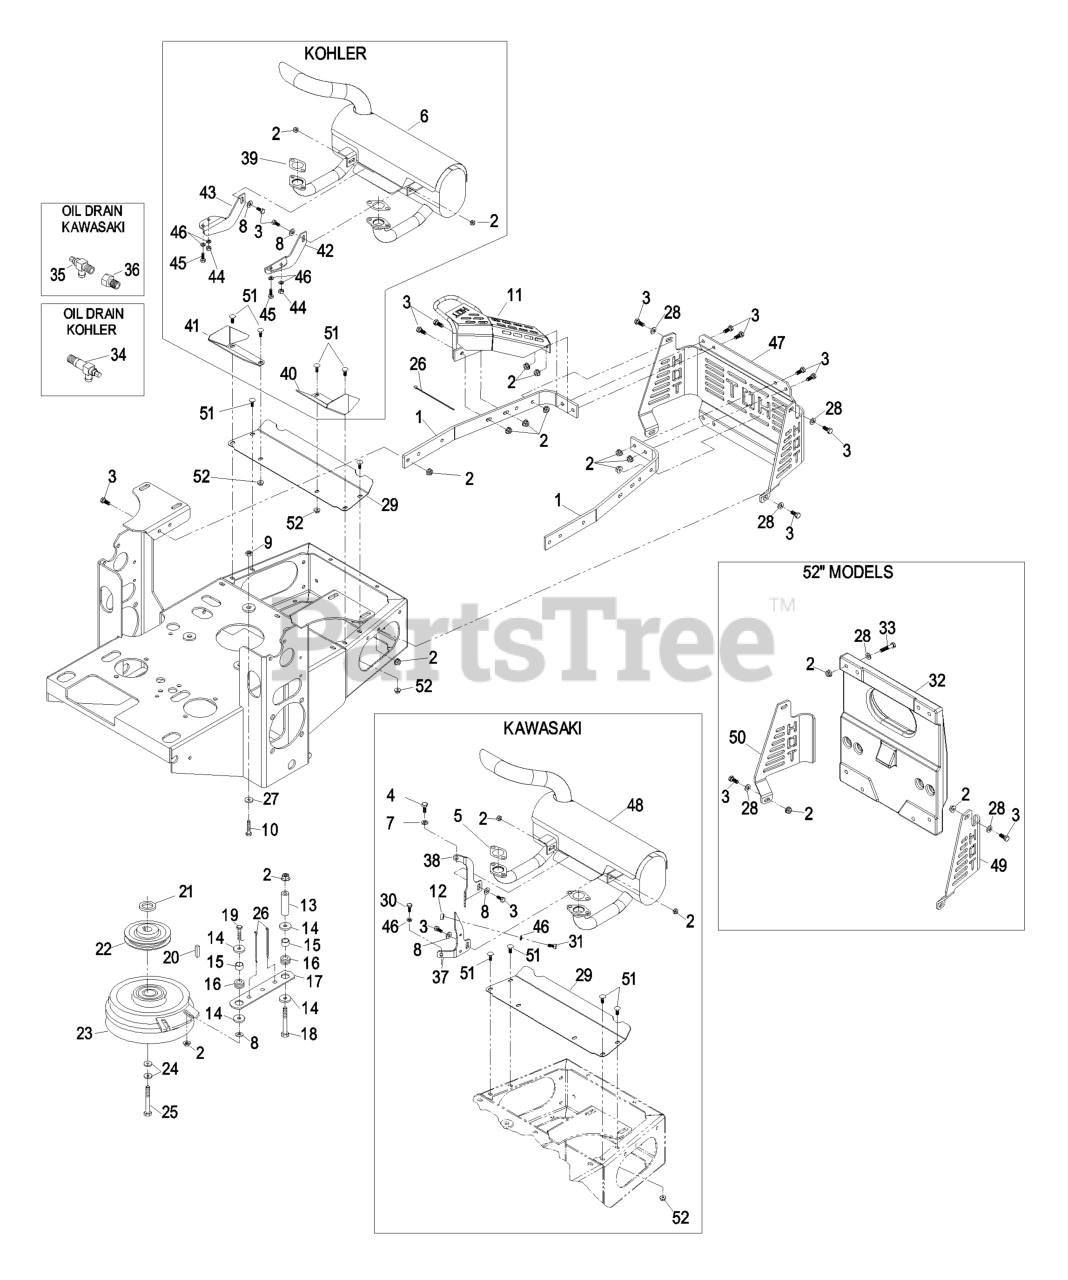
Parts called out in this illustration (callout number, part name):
1	STRAP-GUARD, RH
3	SCREW-HH
4	SCREW-HH
5	GASKET-EXHAUST
6	KIT,MUFFLER (18-23 KOH)
7	WASHER-LOCK
8	WASHER-FLAT
9	NUT-LOCK, NI
10	SCREW-HH
11	GUARD-TAILPIPE
16	GROMMET
17	STRAP-CLUTCH, BRAKE
18	SCREW-HH
19	SCREW-HH
21	SPACER-CRANKSHAFT
24	WASHER-SPRING
25	SCREW-HH
26	TIE-PLASTIC
27	WASHER-SPRING
28	WASHER-PLAIN
29	DEFLECTOR-SHORT
30	SCREW-HH
31	SCREW-HH
33	SCREW-HH
34	VALVE-DRAIN, OIL
35	VALVE-DRAIN, OIL
36	ADAPTER
37	BRACKET-MUFFLER, LH
38	BRACKET-MUFFLER, RH
40	DEFLECTOR-AIR, LH,KC
41	DEFLECTOR-AIR, RH,KC
42	BRACKET-MUFFLER, LH
43	BRACKET-MUFFLER, RH
44	NUT-HEX
45	SCREW-HH
46	WASHER-LOCK
47	GUARD-REAR
48	MUFFLER KIT
49	GUARD-MUFFLER, LH
50	GUARD-MUFFLER, RH
51	SCREW-CARR
52	NUT-HF
